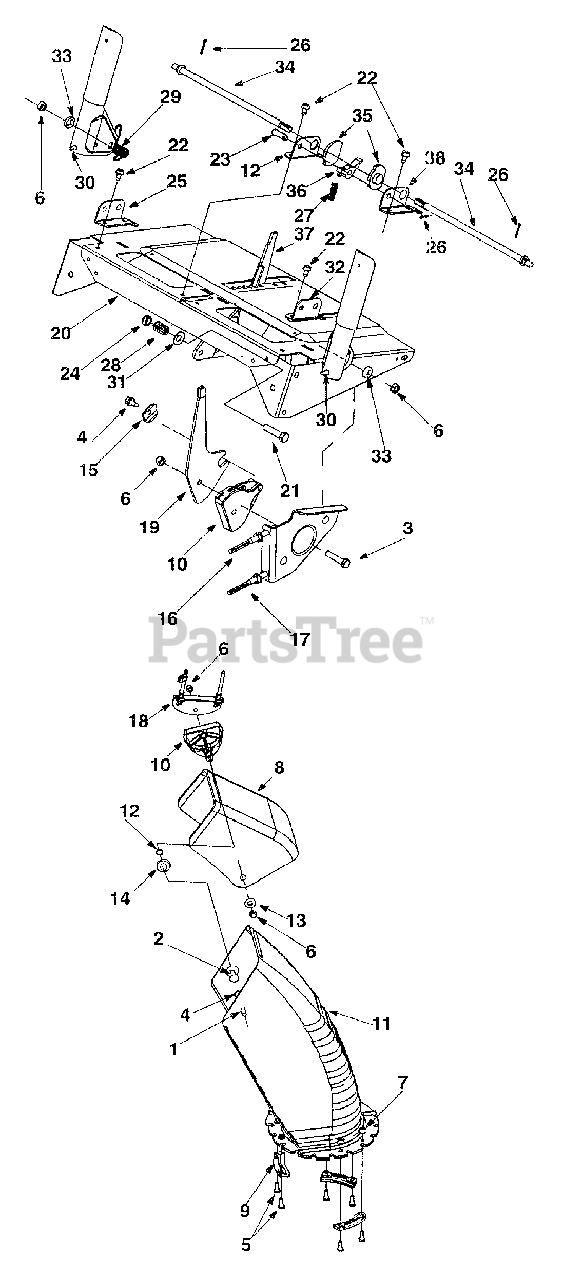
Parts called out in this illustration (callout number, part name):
1	Carriage Screw
2	Carriage Bolt 5/16-18 x 1.75"
3	Hex Bolt 5/16-18 x 1.5"
4	Hex AB Screw 1/4-14 x .625"
5	Hex Screw 1/4-20 x .75"
6	Hex Lock Nut
7	Hex Flange Lock Nut
8	Upper Chute
9	Chute Flange Keeper
10	Cable Guide: Chute Tilt
11	Lower Chute
12	Handle Suppt. Bracket 5/8 RH
13	5/16 Washer
14	Flat Washer
15	Special Washer
16	Chute Control Cable
17	Chute Cable w/Clip
19	Chute Tilt Handle
21	Hex Bolt 3/8-24 x 1.5"
22	TT Screw 1/4-20 x 0.5"
23	Clevis Pin
24	Jam Nut
25	Handle Suppt. Bracket 3/8 RH
26	Cotter Pin
27	Spring
28	Spring
29	Torsion Spring
30	Rubber Bumper
31	Bell Washer
33	Special Washer
34	Cam Rod
35	Cam: Handle Lock
36	Pawl: Handle Lock
37	Shift Handle
38	Handle Suppt. Bracket 5/8 LH
